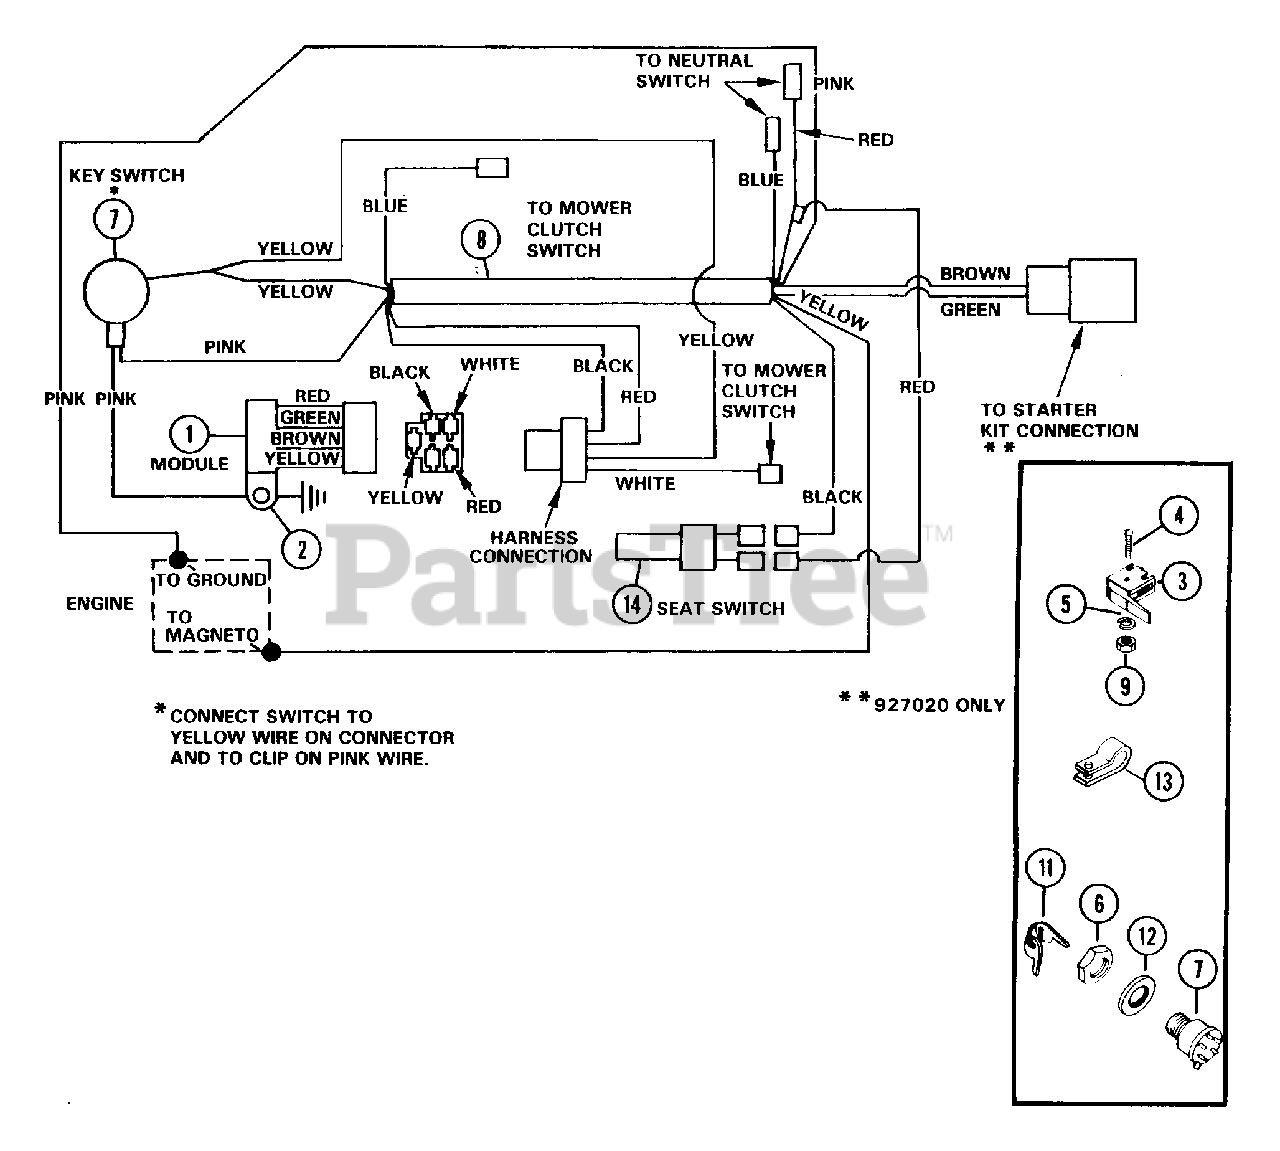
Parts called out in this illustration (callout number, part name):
1	MODULE
2	SCR-TAP 10-12X.50 CRPH PL A
3	SWITCH INTERLOCK
4	SCR-MCH 10-24X1.00 SLRH PL
5	WSHR-LK 10X.047 MED PL
6	NUT .625-32 ALUM
7	SWITCH & KEY SET ASSEMBLY
8	WIRING HARNESS
9	WIRE HARNESS
9	NUT-HEX 10-24 PL
11	KEYS
12	WSHR-LK-INT .625X.045 PL
14	SWITCH SEAT
